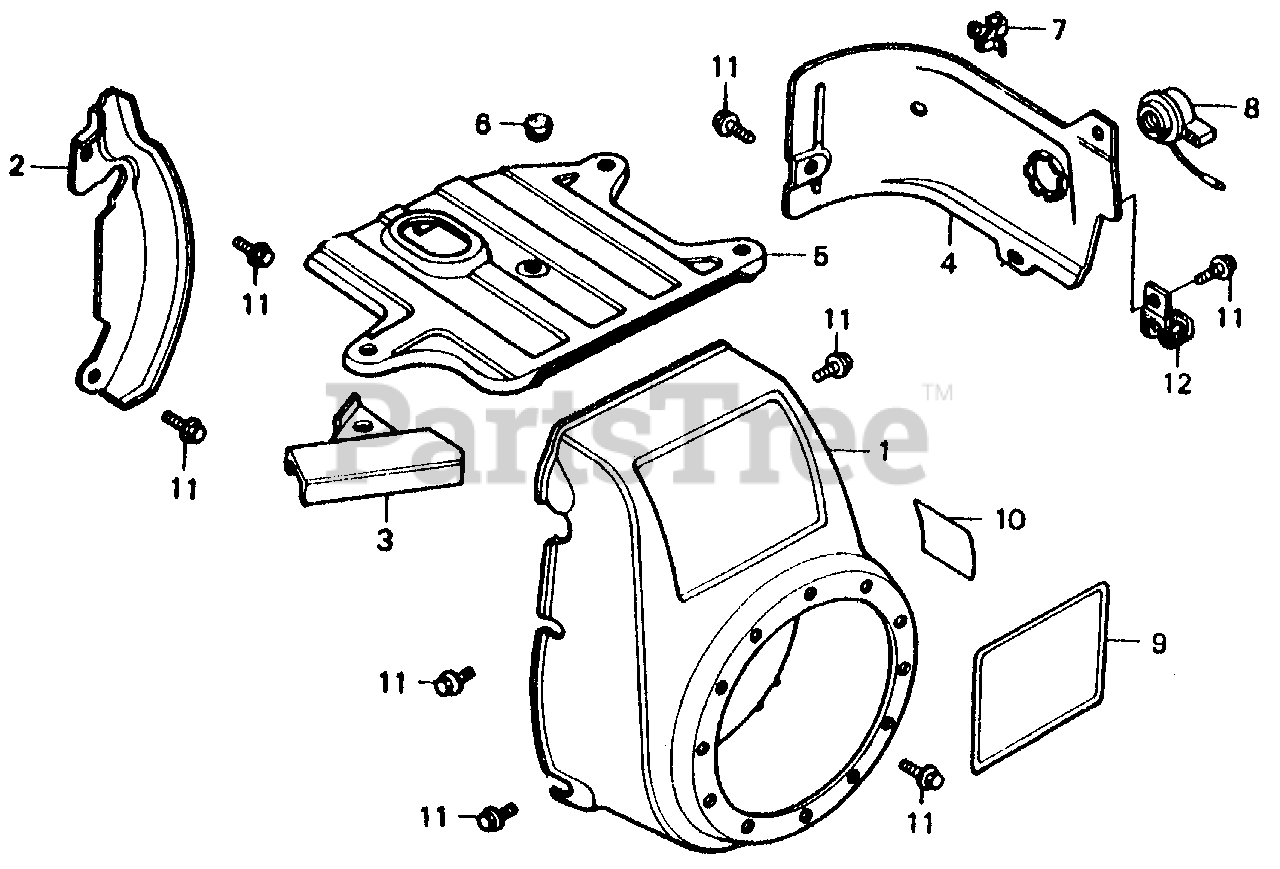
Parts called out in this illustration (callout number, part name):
1	COVER, FAN *R8* (BRIGHT RED)
2	PLATE, SIDE
3	GUIDE, AIR
5	COVER, TOP
6	GROMMET, TOP COVER
7	CLIP, IGNITION WIRE (8MM)
8	SWITCH ASSY., ENGINE STOP
9	EMBLEM (NOT AVAILABLE)
10	MARK, OIL CAUTION
11	BOLT, FLANGE (6X12) (CT200)
12	CLIP, CABLE
